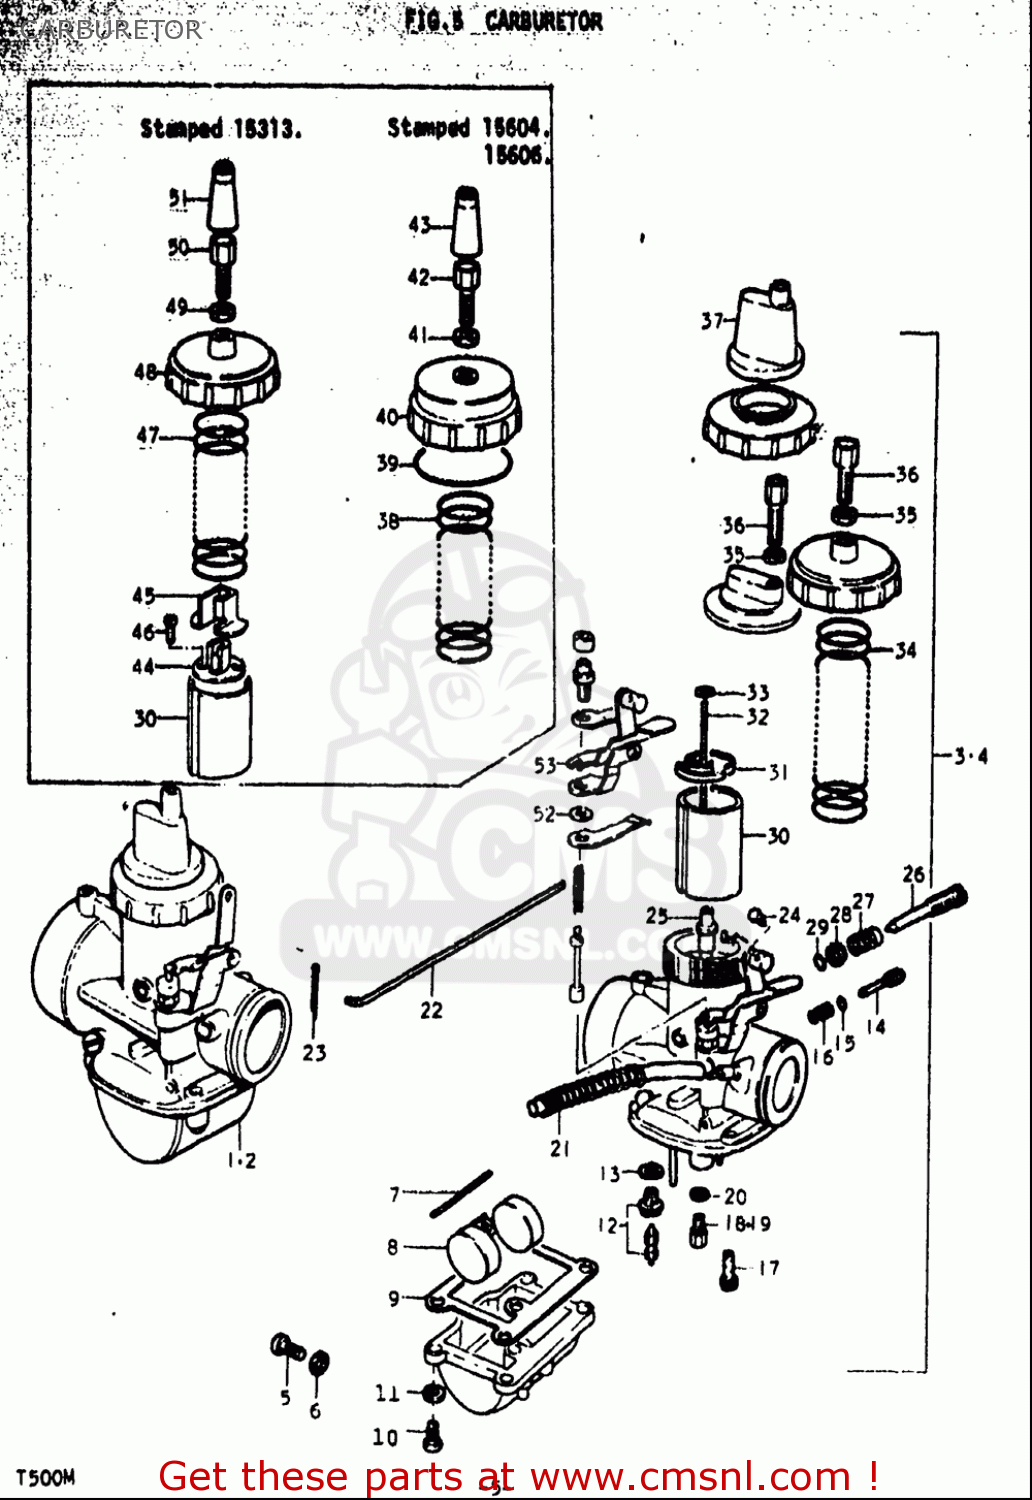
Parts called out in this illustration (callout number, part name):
5	PLUG
6	GASKET,DRAIN,PLUG (NAS)
7	PIN,FLOAT
8	FLOAT
9	GASKET,FLOAT CAHMBER (NAS)
10	SCREW 4X16
11	WASHER,LOCK
12	VALVE ASSY,NEEDLE
13	GASKET,MAIN JET HOLDER (NAS)
14	SCREW,PILOT AIR
15	O RING
16	SPRING
17	JET,PILOT(30)
18	JET,MAIN(150)
19	JET,MAIN
20	WASHER
21	HOSE(4.5X8.5X600)
22	ROD,STARTER LEVER
23	PIN 12X10
24	BOLT, STARTER ROD
26	SCREW,THROTTLE STOP
27	SPRING,THROTTLE STOP
28	COVER
29	O RING
33	CLIP
35	NUT
36	ADJUSTER,CABLE
44	CONNECTOR
46	SCREW
49	NUT
50	ADJUSTER,CABLE
51	CAP,CABLE ADJUSTER
52	O RING(D:1.5,ID:8.5)
